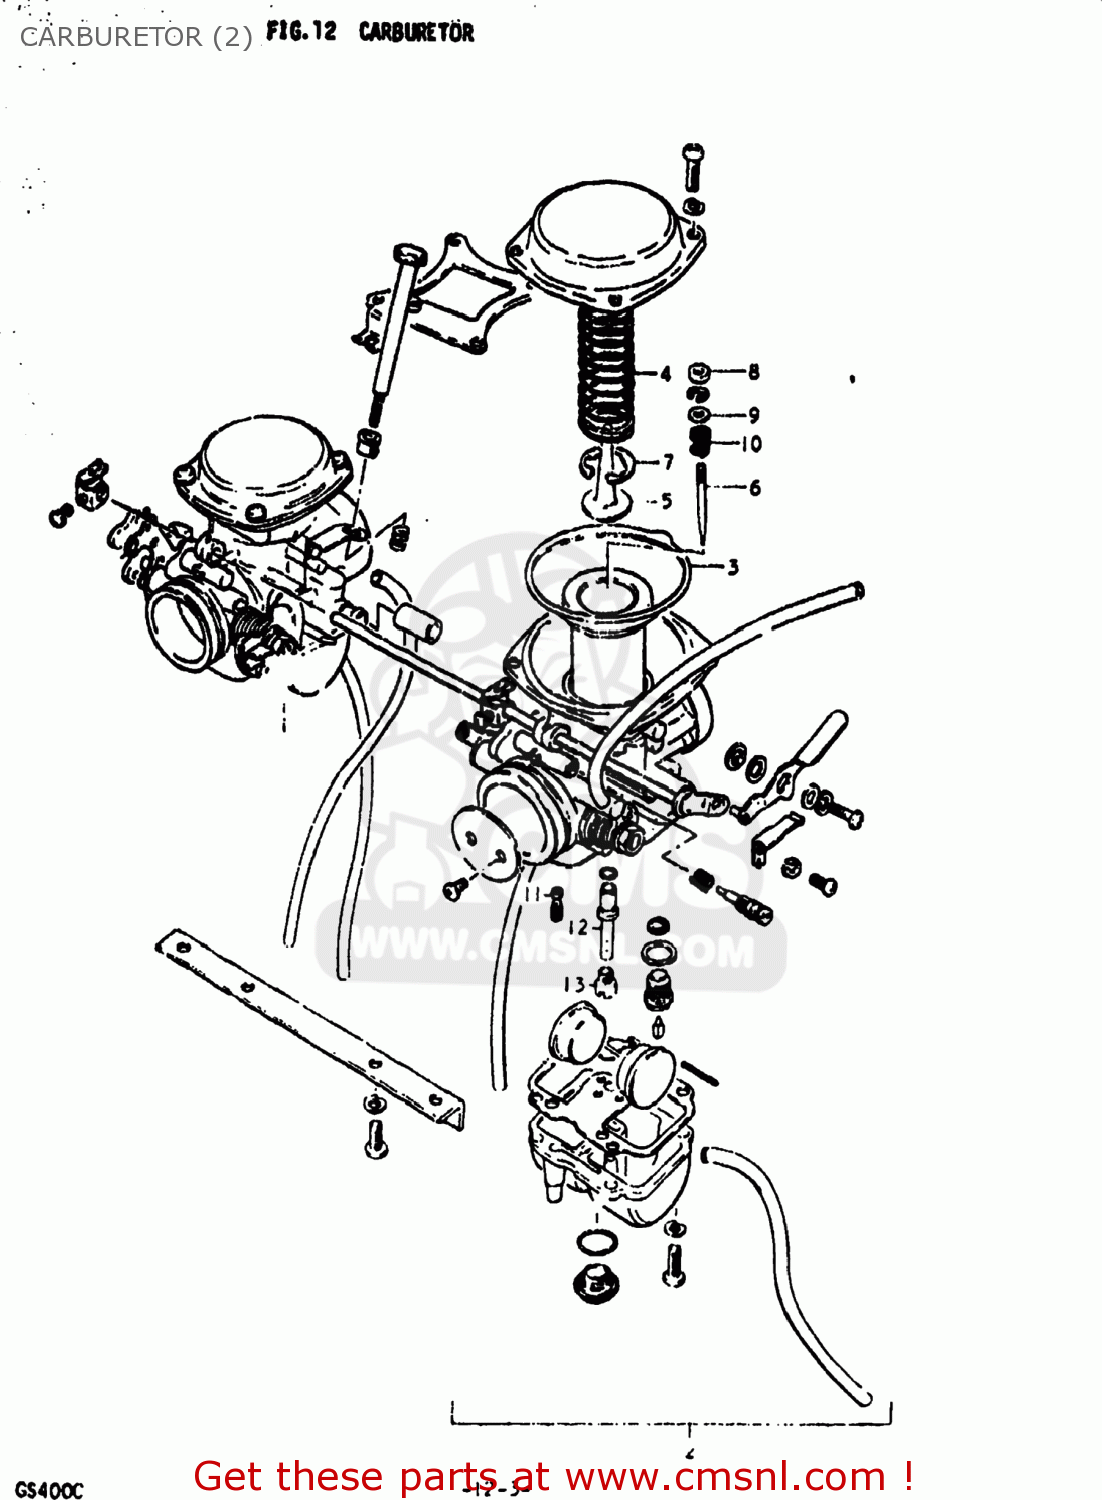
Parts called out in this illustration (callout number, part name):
1	CARBURETOR ASSEMBLY
2	CARBURETOR ASSEMBLY
3	DIAPHRAGM ASSEMBLY
4	SPRING,DIAPHRAGM
5	HOLDER,GUIDE
6	NEEDLE JET
7	E RING
8	RING
9	WASHER
10	SPRING
11	JET,PILOT
12	JET,NEEDLE
13	JET,MAIN(110)
